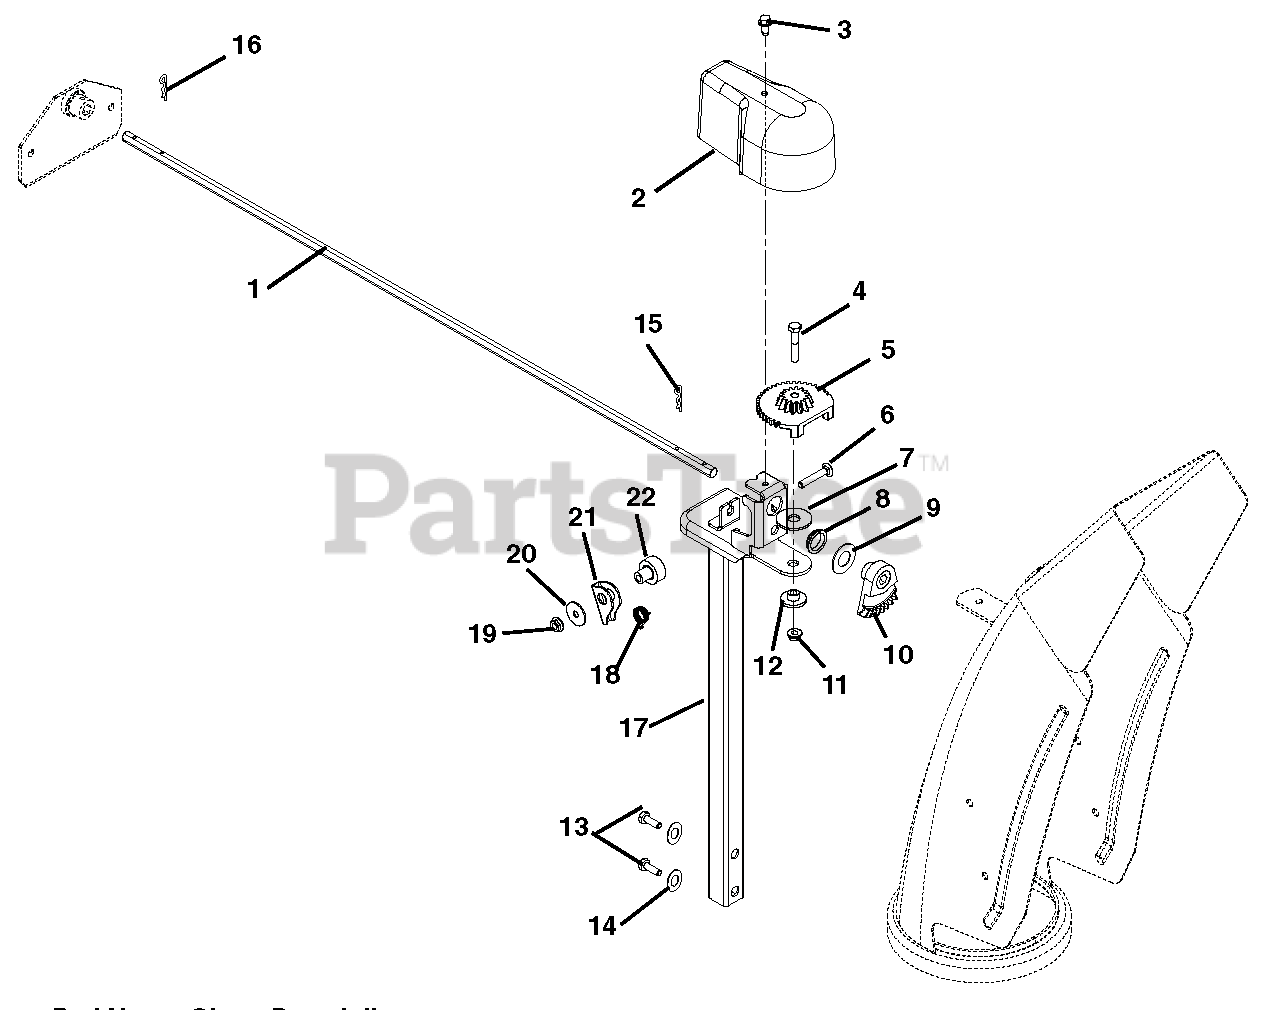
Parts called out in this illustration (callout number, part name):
1	ROD, CHUTE ROTATION-HEX
2	COVER, CHUTE GEAR
3	SCR-TAP .25-20X.50 HWH TR YWZ
4	@BLT-HEX .25-20X1.50 GR5 YWZC
5	GEAR, CHUTE
6	@BLT-RDHDSQNK .25-20X1.50 G5YZ
7	WSHR-FL-NYL .47X1.38X.09
8	BUSHING, POLYLINER-.75 SNAPIN
9	WSHR-FL-STL.754X1.125X.062YWZC
10	GEAR, CHUTE-ACTUATION
11	@NUT-LK-TOP-FLG .25-20 YWZC
12	BSHG-FLG .265X.384X.375X1.00
13	@BLT-HEX .38-16X1.75 GR5 YWZC
14	@WSHR-LK .38X.094 REG YWZC
15	CLIP, SPRING
16	HAIRPIN, #7 CLIP .094X2.31 YWZ
17	PEDESTAL, CHUTE-QUICK STICK
18	SG-TORS
19	@NUT-LK-TOP-FLG .25-20 YWZC
20	WSHR-FL-STL .281X1.000X.063
21	ARM, LOCKING
22	BUSHING, LOCK ARM
